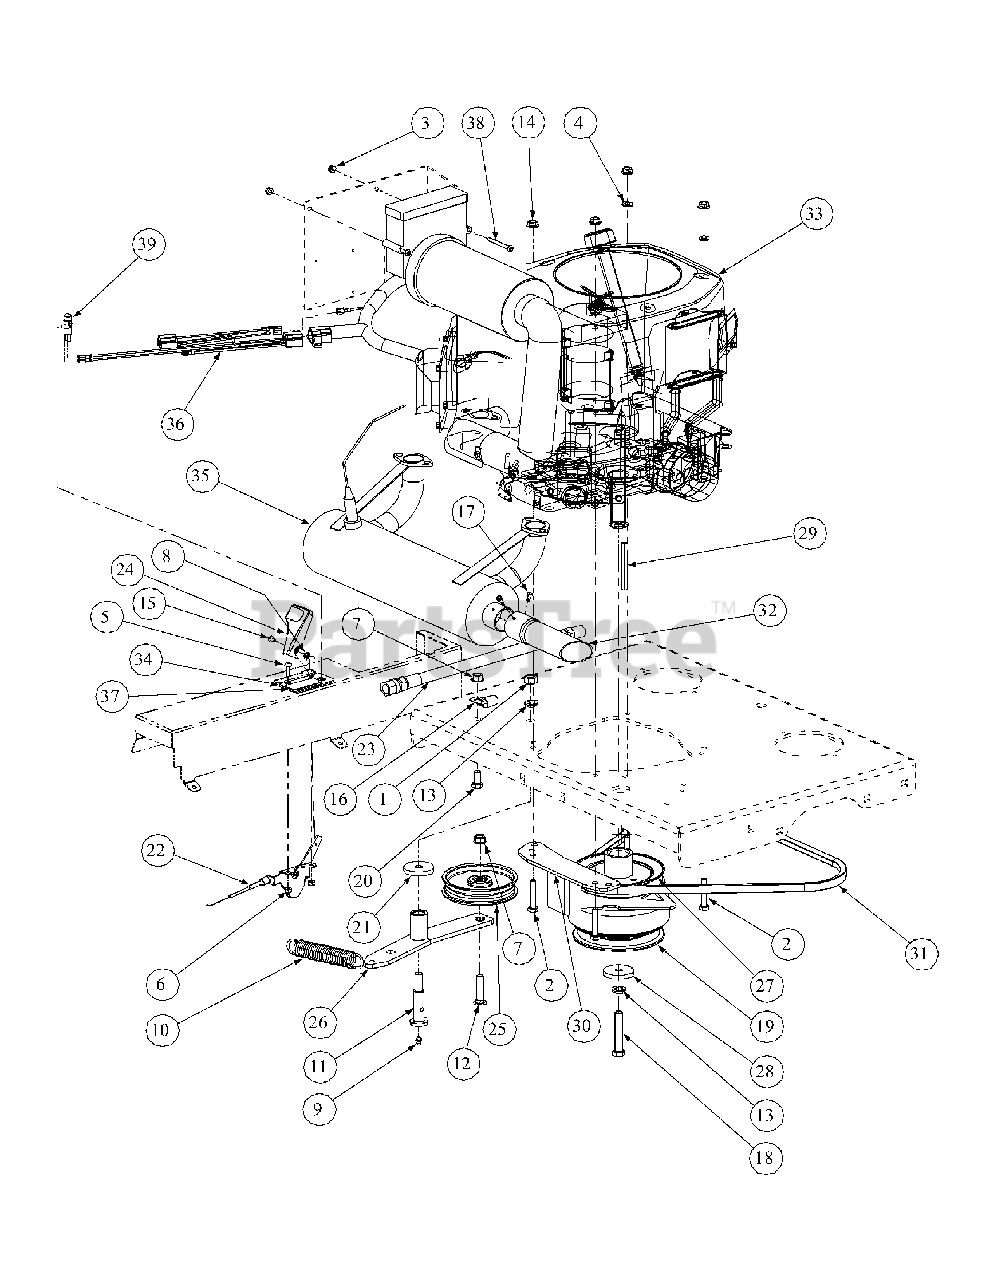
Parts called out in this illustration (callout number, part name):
1	Hex Nut, 7/16-14
2	HHCS, 5/16-18, 1-3/4
3	Nut, 10-24, Nylon Insert
4	Flat Washer, 5/16
5	Round Hd. Machine Screw, 10-32 x 3/4
6	Lock Nut, Nylon Insert, 10-32
7	Flange Lock, Hex Nut, 3/8-16
8	Nut Washer, W/Star, 8-32
9	Grease Fitting, 1/4-28 x 3/16
10	Extension Spring, 1.0 OD x 5.125
11	Shoulder Screw, 7/16-14
12	Hex Carriage Screw, 3/8-16, 1.75
13	Lock Washer, 7/16
14	Hexflange Lock Nut, 5/16-18
15	Machine Screw, 8-32, .375
16	Clip, Heat Shield Cable
17	Screw, #8-32, 0.375 Hxindwsh
18	Capscrew, 7/16-20 x 2.50
19	Clutch Brake, 1.125 ID
20	Hex Cap Screw, 3/8-16, .750
21	Flat Washer, 7/16 ID x 1.75 OD x .25
22	Throttle Control Cable
23	Oil Drain Hose
24	Control Throttle Knob
25	Flat Pulley with Flanges
26	Engine Idler Arm Assembly includes Bearing
27	Pump Drive Pulley
28	Flat Washer, 7/16 ID x 1.75 OD x .25
29	Key, 1/4 x 1/4 x 3
30	Retainer Clutch Assembly, Ogura
31	Belt, 51.2 Lg
32	Straight Exhaust Pipe, Selxsys
33	Engine, 28HP Kohler E.F.I.
34	Light Indicator Plate
35	Muffler, Kohler E.F.I.
36	Wire Harness Adaptor
37	Decal, Engine Blink Code
38	Machine Screw, 10-24 x 2.0
39	Light Indicator, 12V
